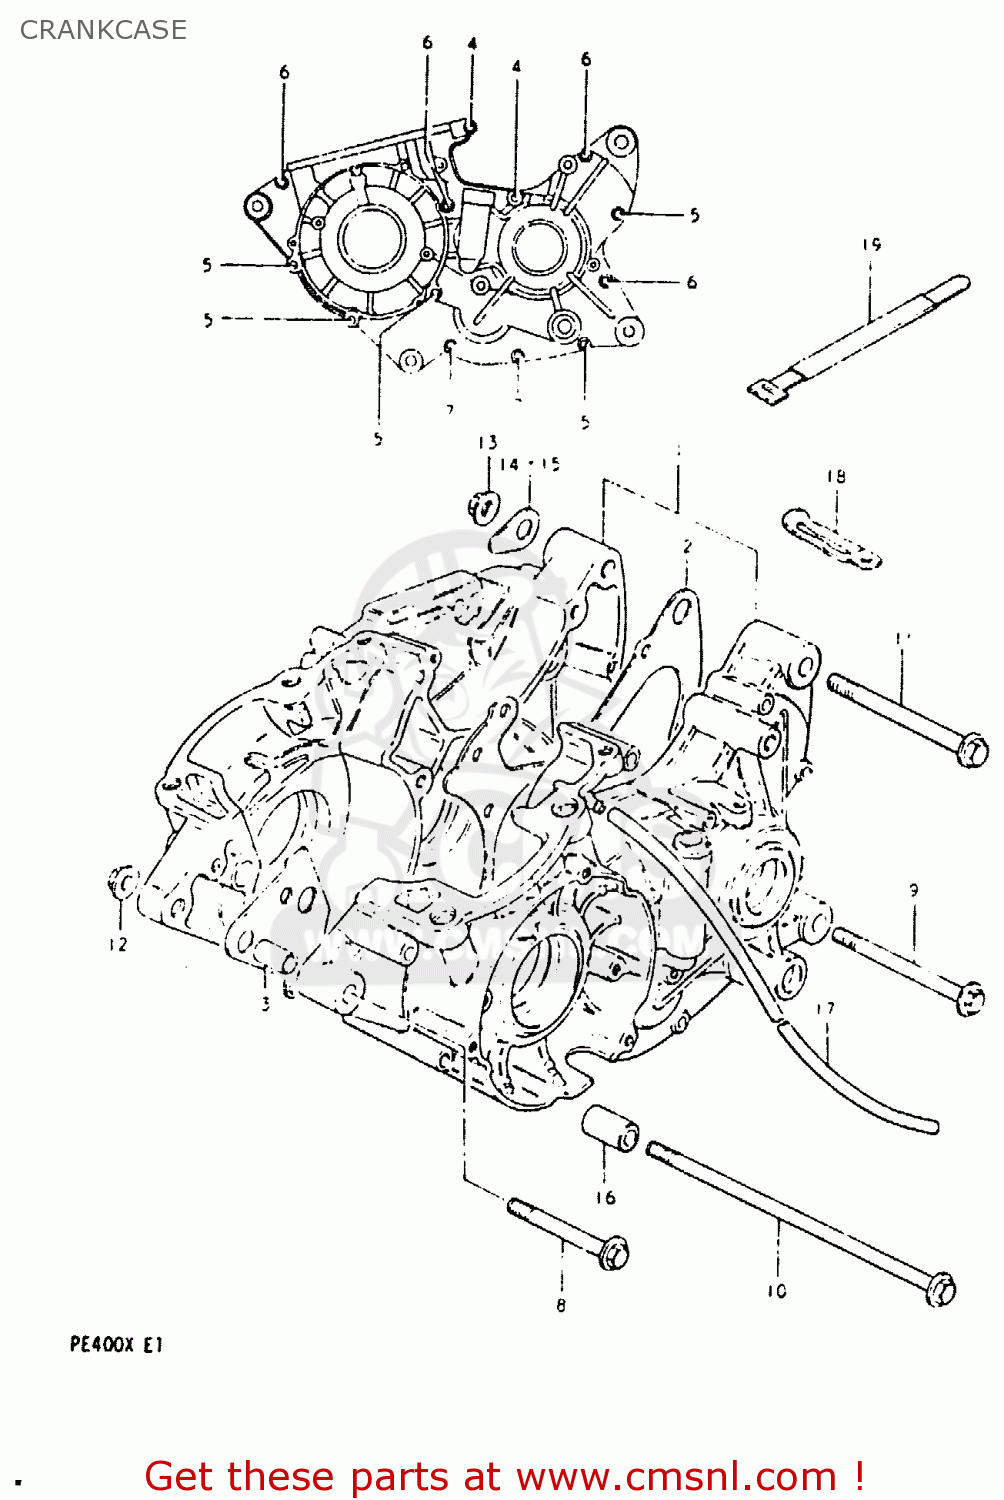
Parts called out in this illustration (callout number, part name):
1	CRANKCASE SET
2	GASKET,CRANKCASE (MCA)
3	PIN
4	CROSS SCREW (6 X 75)
5	SCREW 6X60
6	SCREW
7	SCREW (6X35)
8	BOLT(8X67)
9	BOLT
10	BOLT
11	BOLT
12	NUT
13	NUT
14	WASHER
15	WASHER
16	SPACER(8.6X16X26)
17	HOSE
18	CLAMP
19	CLAMP
